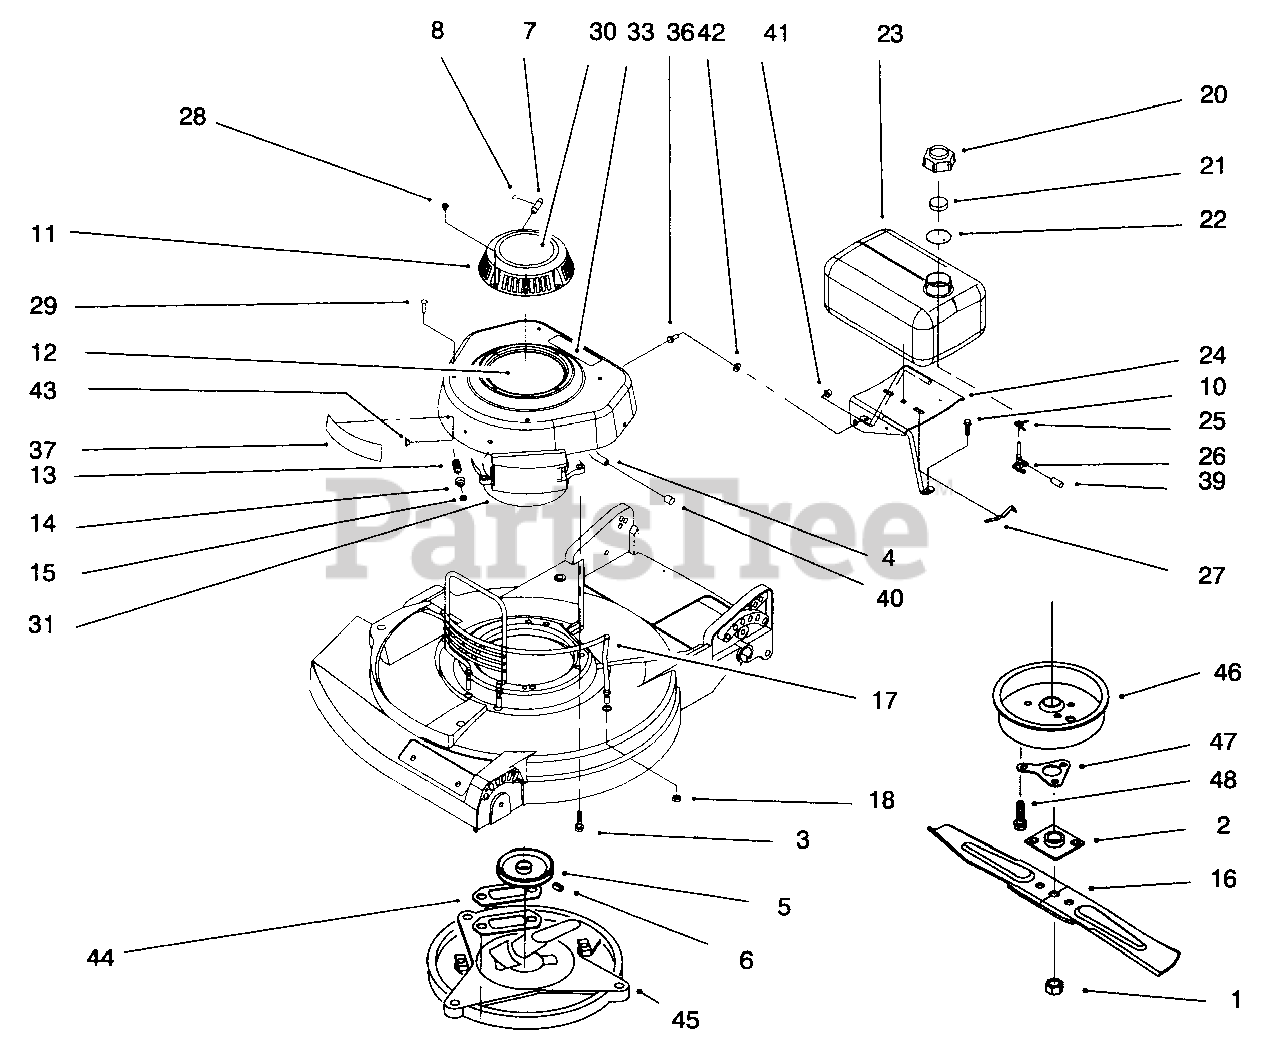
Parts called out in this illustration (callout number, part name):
1	Nut-Blade
2	Plate & Collar Assembly
3	Screw-Engine Mount
4	Hose-Gas
6	Screw-Set
7	Rope-Stop
8	Staple
10	Screw-Hex Washer Hd.
11	Housing-Starter
12	Shroud Assembly
14	Actuator-Brake Lever
15	Retainer
16	Blade-21"
17	Guard-Engine
18	Nut-Lock
20	Cap-Fuel
21	Foam-Baffle
23	Tank-Fuel
24	Leg & Saddle Assembly
25	Clamp-Hose
26	Valve & Screen
28	Screw-Sems
29	Screw-Thr'd Form
30	Decal-Recoil
31	Engine-2 Cycle
33	Decal-Oil
36	Screw-Carriage
37	Applique
39	Plug-Fuel Valve
40	Plug-Fuel Line
41	Nut-Lock
42	Washer-Flat
43	Retainer-Applique
44	Gasket-Muffler
45	Plate-Muffler
46	Muffler Cover Assembly
47	Support-Crankshatt
